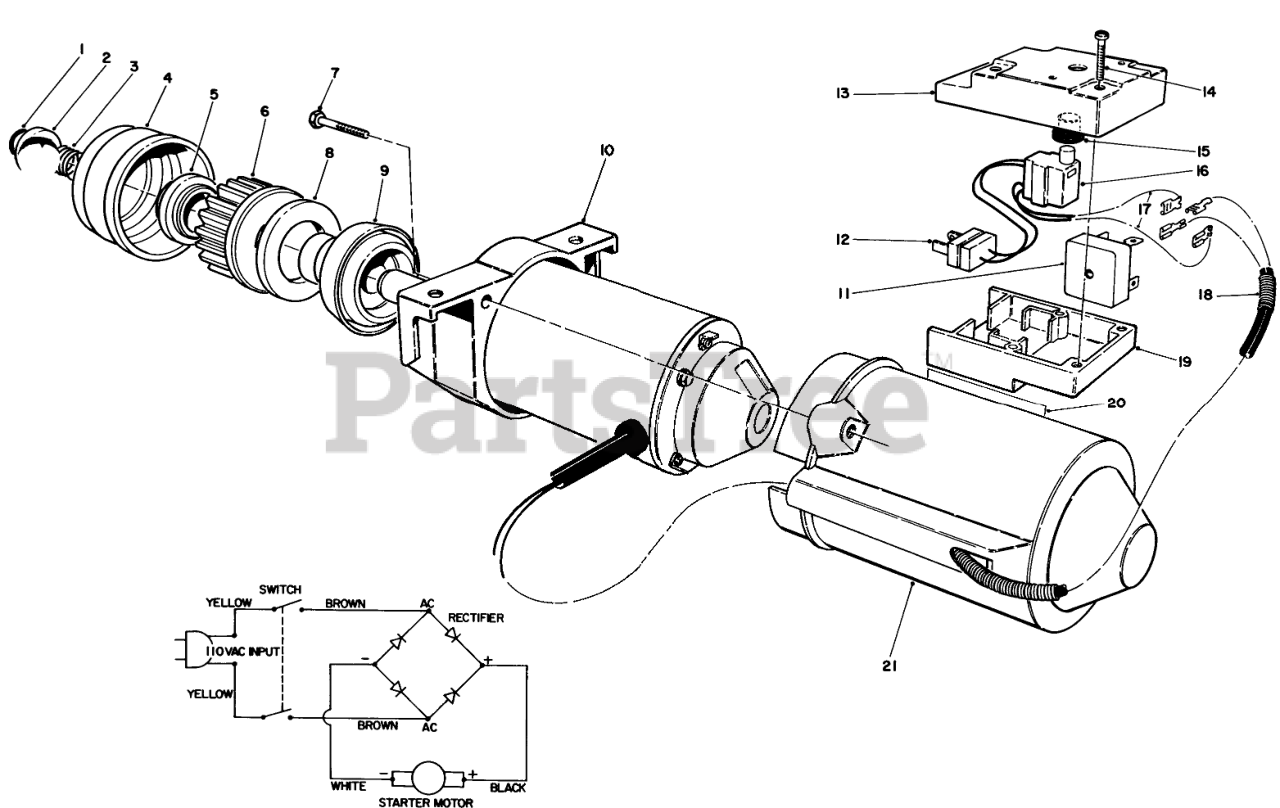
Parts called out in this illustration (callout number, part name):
1	RING-LOCK
2	PINION STOP
3	SPRING
4	Retainer
6	Gear-Pinion
7	Screw-Plastite
8	Ring-Rubber
9	Drive-Pinion
10	Starter Motor Assembly (Incl. Ref. #1-6, 8 & 9)
11	RECTIFIER-BRIDGE
12	Plug
13	SWITCH BOX CAP
14	Screw-Plastite
15	BOOT-SWITCH
16	SWITCH-STARTER
18	CABLE COVER
19	SWITCH BOX BASE
20	Decal-UL
21	STARTER MOTOR COVER
